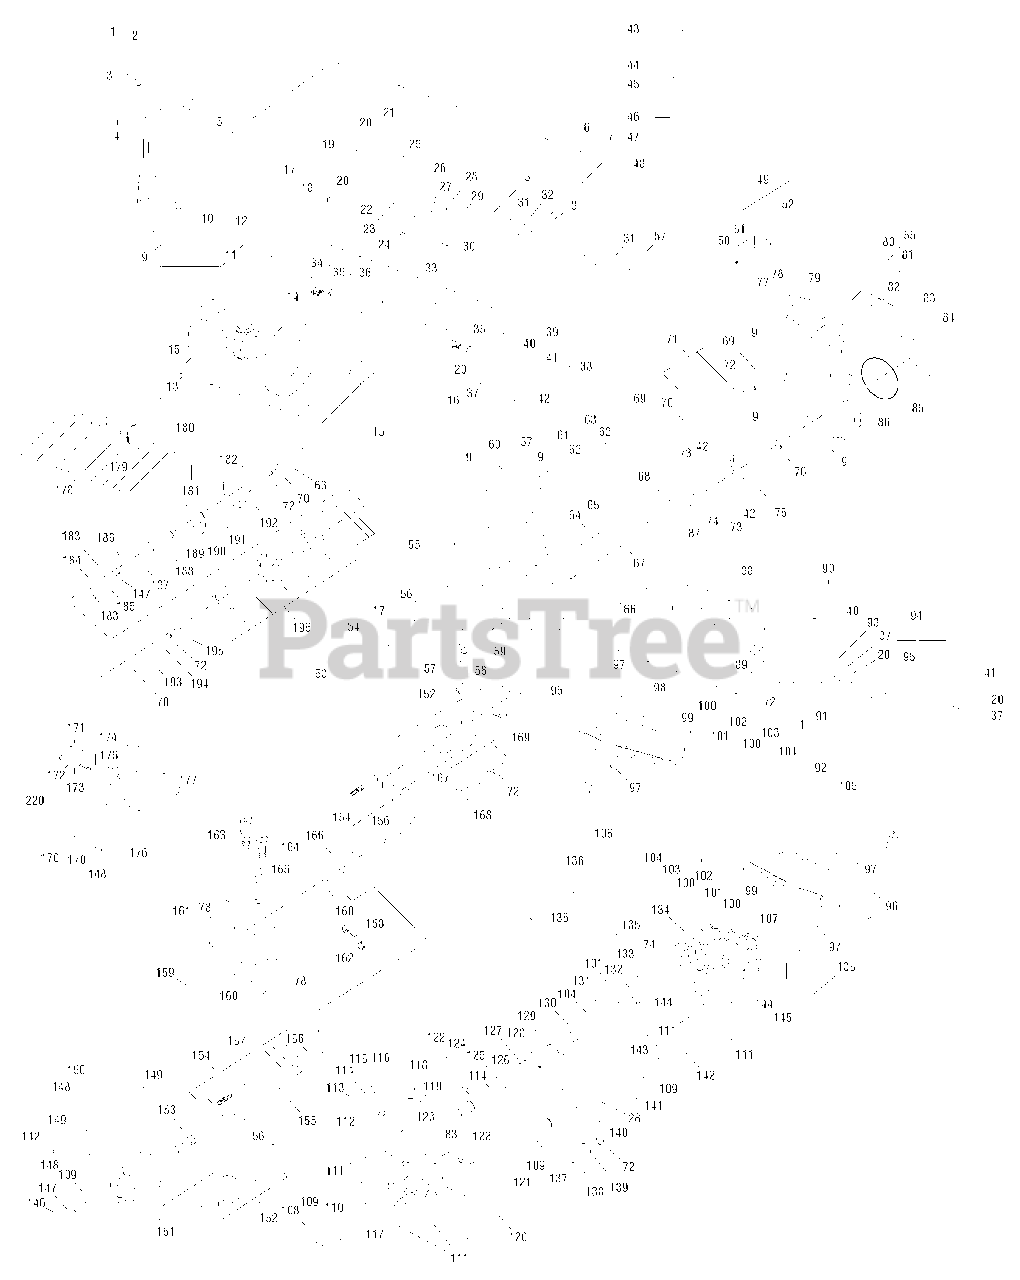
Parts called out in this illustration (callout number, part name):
2	COVER PTO BRAKE
5	COVER KIT MISSION
6	O-RING, 1A P10A
8	SPRING CENTERING
9	COLLAR 8*10*11.5
10	BEARING TMB305
11	FINAL GEAR KIT
12	SHAFT FINAL PINION
13	DIFF GEAR KIT
15	BEARING 6007
16	SLIDER DIFF LOCK
17	GEAR KIT INPUT
18	BEARING 6005SH2
21	ABSORBER SHOCK
23	WASHER 44*14*4.5
24	PUSH NUT 7.8
26	ARM CONTROL
28	WASHER 29*35*1
29	PACKING P26
30	PIN ARM CONTROL
31	WASHER 38*38*2
33	FORK KIT DIFF LOCK
34	SPACER 16.5*24*1
36	PIN 4.0A*25
38	FULCRUM KIT DIFF
44	PACKING P18
45	PIPE OIL PORT
47	TAPPING SCREW 8*20
48	PACKING P32
49	SOLENOID ASSY
50	GASKET SOLENOID
51	VALVE ASSY SOLENOID
52	PACKING P18
54	BEARING TMB303C
57	HOUSING KIT MISSION
59	SEAL TC253807
61	PACKING 19017
63	BEARING 6004
66	SEAL TC162606
67	NEEDLE 253216 NTN
68	SHAFT MID PTO
69	BEARING 6204
71	IDLE ASSY PTO
73	WASHER 8.5*24*4
74	BEARING 6205
75	GEAR Z=62T MID PTO
81	SOLENIOD SPRING
82	PTO RELIEF VALVE KIT
85	REAR COVER PLATE
86	PACKING G130
87	PLATE KIT BRAKE
91	PACKING P16
92	CAM BRAKE KIT
96	COLLAR 10*12*20
98	REAR AXLE HOUSING R
100	COLLAR 30*42*2
101	BEARING 6006
102	SLEEVE 30*39*16
103	SEAL TC395511
105	SHAFT REAR AXLE R
106	SHAFT REAR AXLE L
107	REAR AXLE HOUSING L
108	SEAL TC254208
109	BEARING 6005
110	BOLT M12*12
112	SHAFT SHIFT 4WD
113	PIN 3.5A*25
114	PIN 6.0A*25
115	PACKING P12.5
116	ARM SHIFT 4WD
117	GASKET 20*12*2
121	FRONT COVER
123	SHAFT FRONT DRIVE
124	SPRING 21.2
125	ARM SHIFT 4WD
126	BLOCK SHIFT FRONT
127	COLLAR FRONT SHIFT
129	GEAR 26T 4WD
131	COLLAR 30*38*4
133	COLLAR 30*38*9.2
134	CENTER PLATE
136	PK 4WD GEAR BOX
137	SHAFT REDUCTION 4WD
138	BEARING 6004
139	GEAR 13T MOTOR
140	GEAR 34T 4WD
141	GEAR 30T 4WD
142	BOLT 10*145
143	BOLT 10*180
145	PACKING FRONT COVER
148	BOLT 10*105
149	PIN KNOCK 12*22
150	PACKING MOTOR CASE
151	MOTOR CASE CMP.
152	BEARING SET THRUST
153	SHAFT MOTOR
154	BLOCK ASSY. CYL. P
155	PLATE VALVE M
157	CENTERCASE ASSY.
158	BODY ASSY. SUCTION
161	PACKING KIT
162	CENTERCASE PACKING
163	RELIEF ASSY. TOW 32
164	VALVE ASSY. CHECK R
165	RELEASE ASSY IMPLE
166	PLATE VAVLE P
171	VALVE ASSY.
174	PLUG 1/2OUNF
175	PACKING AS 905
176	BODY ASSY. PUMP
177	VALVE ASSY. REDUCING
178	BRAKE KIT PTO
179	PACKING 2045
180	PACKING P10
181	COLLAR BRAKE PIN
182	SHOE PTO BRAKE
184	NEEDLE 121718
185	WASHER 13*17*1
186	WASHER 25*42*2
187	SPRING PTO RETURN
188	SHAFT CLUTCH
189	RING SEAL 17203
191	PACKING G75
192	GEAR CLUTCH Z=39
194	WASHER 20*34*1
195	COLLAR SPLINE
196	DISC KIT FRICTION
220	SEAL, Charge Pump
